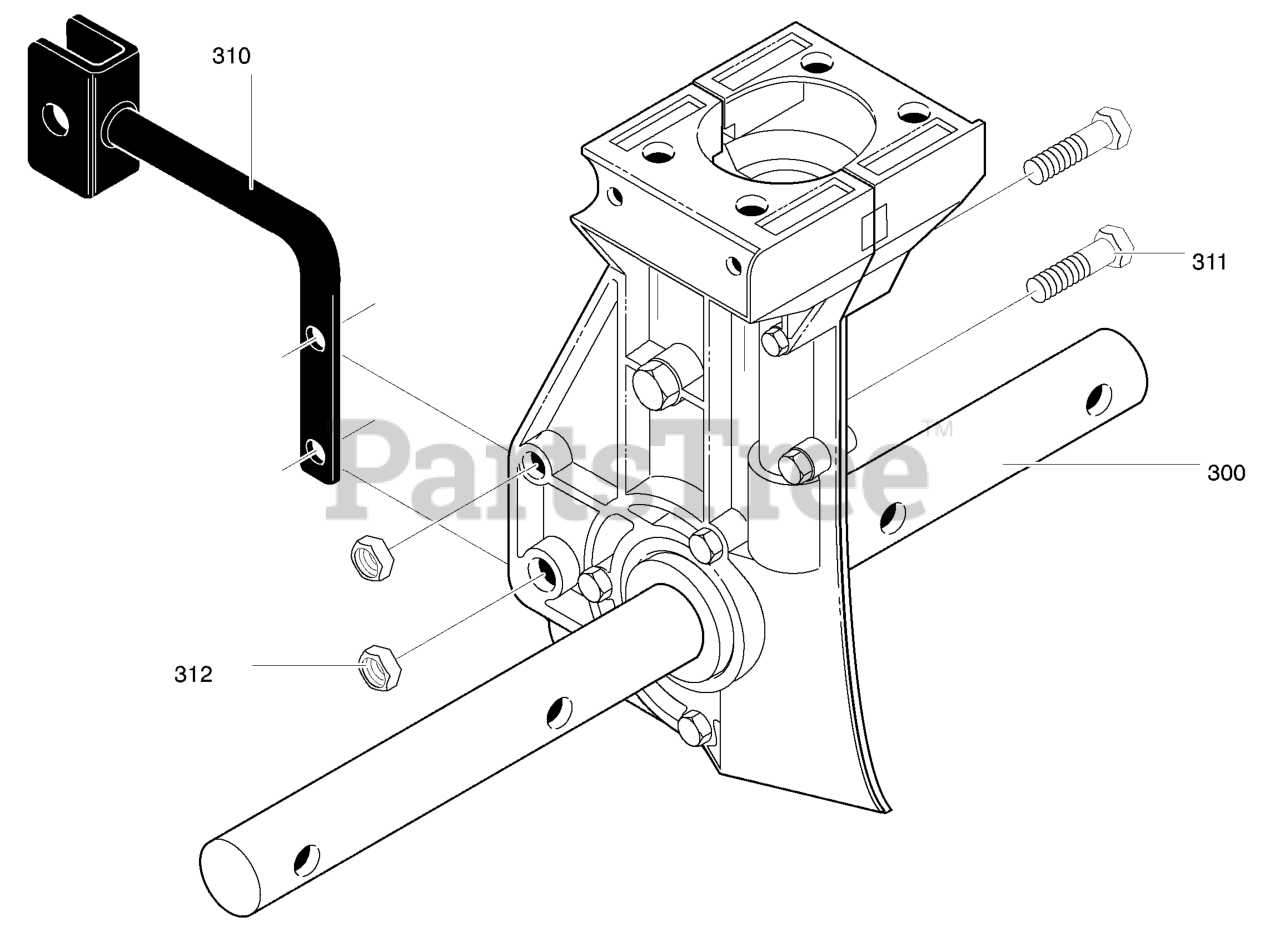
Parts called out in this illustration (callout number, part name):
300	Transmission
310	Bracket, Depth Rod
311	Screw, 1/4-20x1.25
312	Nut, 1/4-20
